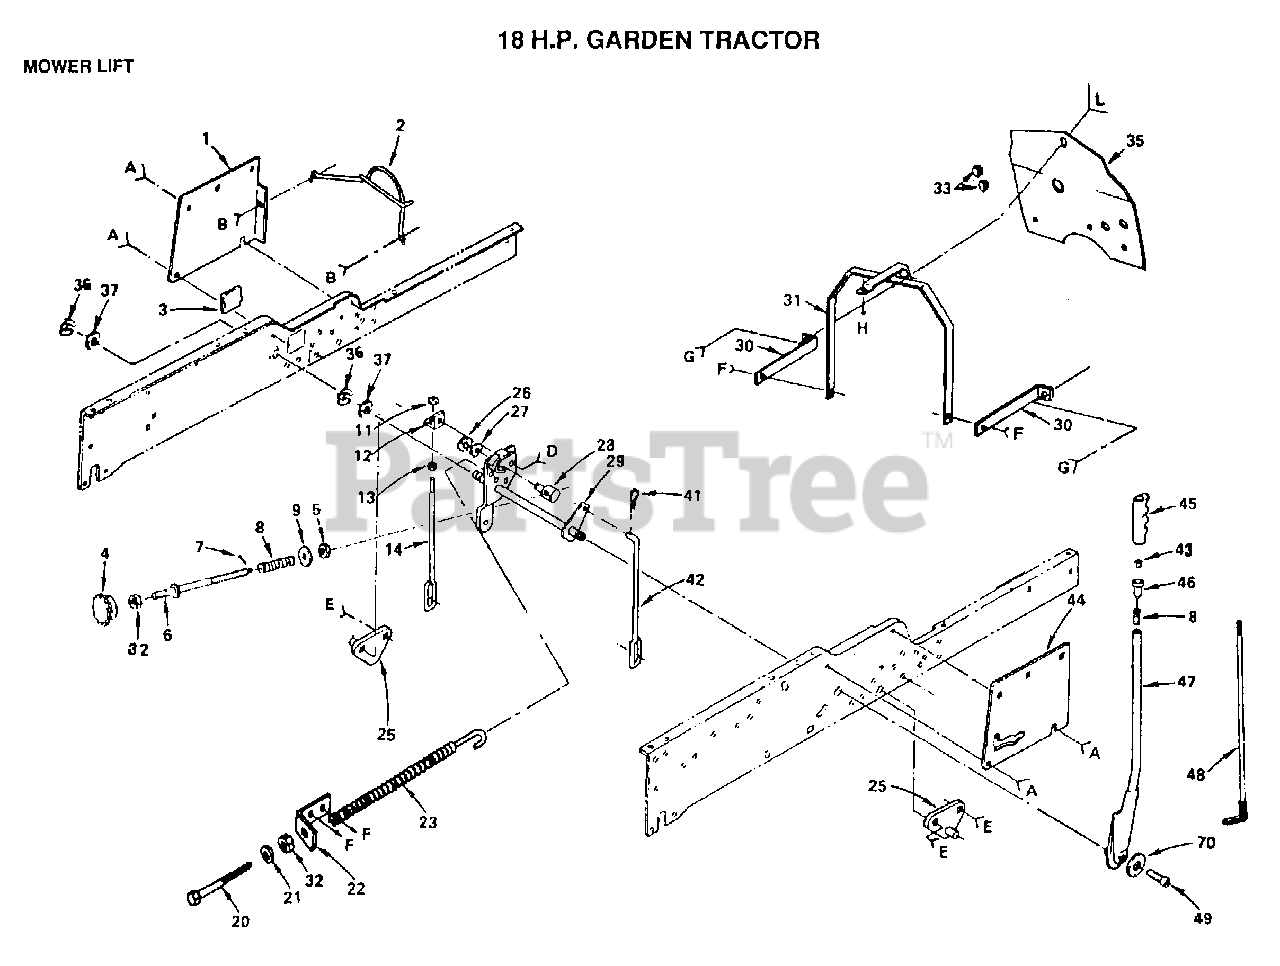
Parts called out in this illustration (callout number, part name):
3	COVER ACCESS
4	HDLE ADJ LIFT
5	NUT T
6	ROD ADJ. T
8	SPRING T
9	WASHER
11	NUT
12	BRACKET T
13	NUT.HEX.3/8-16UNC
14	LINK-LIFT MOW T
20	BOLT-ADJ SPRING T
21	WASHER
25	SUSP BRACKET T
26	KLIP RING
27	WASHER
28	TRUNION LT
30	BRACKET T
32	NUT
35	"SHIELD HEAT, BASE"
36	E-RING
37	WASHER
42	LIFT LINK RH T
45	GRIP
48	LEVER ROD LT
49	"BOLT,HEX"
70	LOCKWASHER
